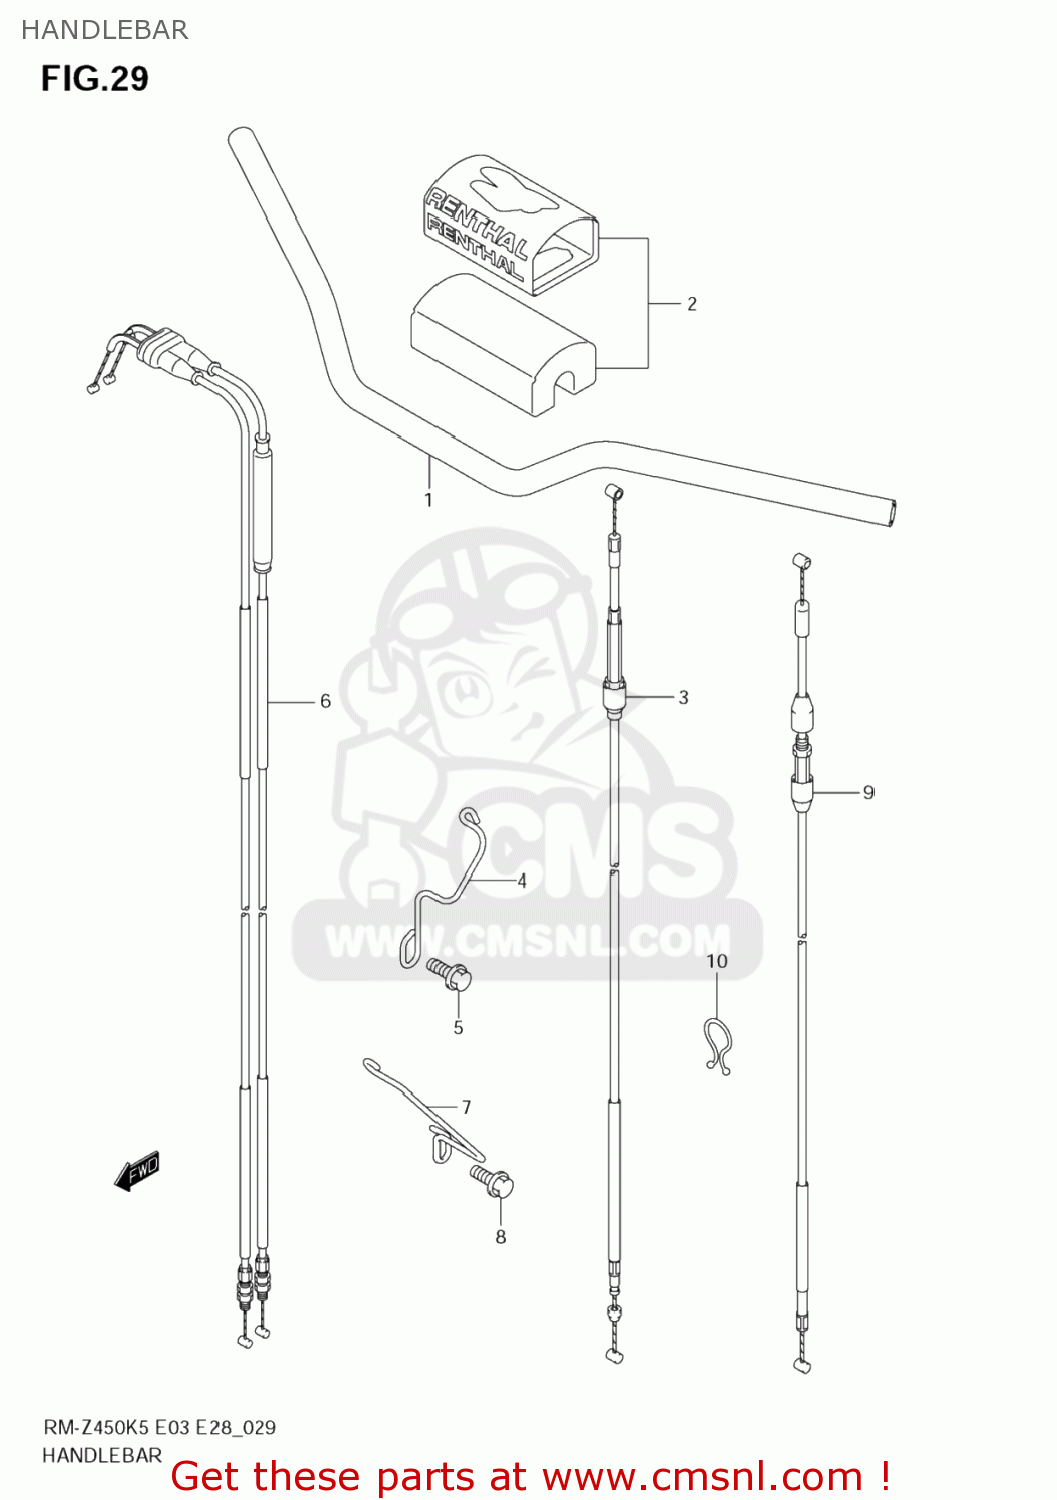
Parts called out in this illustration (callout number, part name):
1	HANDLEBAR
2	PAD SET,HANDLEBAR (NAS)
3	CABLE ASSY,CLUTCH
4	GUIDE,CLUTCH CABLE
5	BOLT(6X16)
6	CABLE SET,THROTTLE
7	GUIDE,THROTTLE & CLUTCH CABLE
8	BOLT(6X16)
9	CABLE ASSY,HOT STARTER
10	CLAMP
